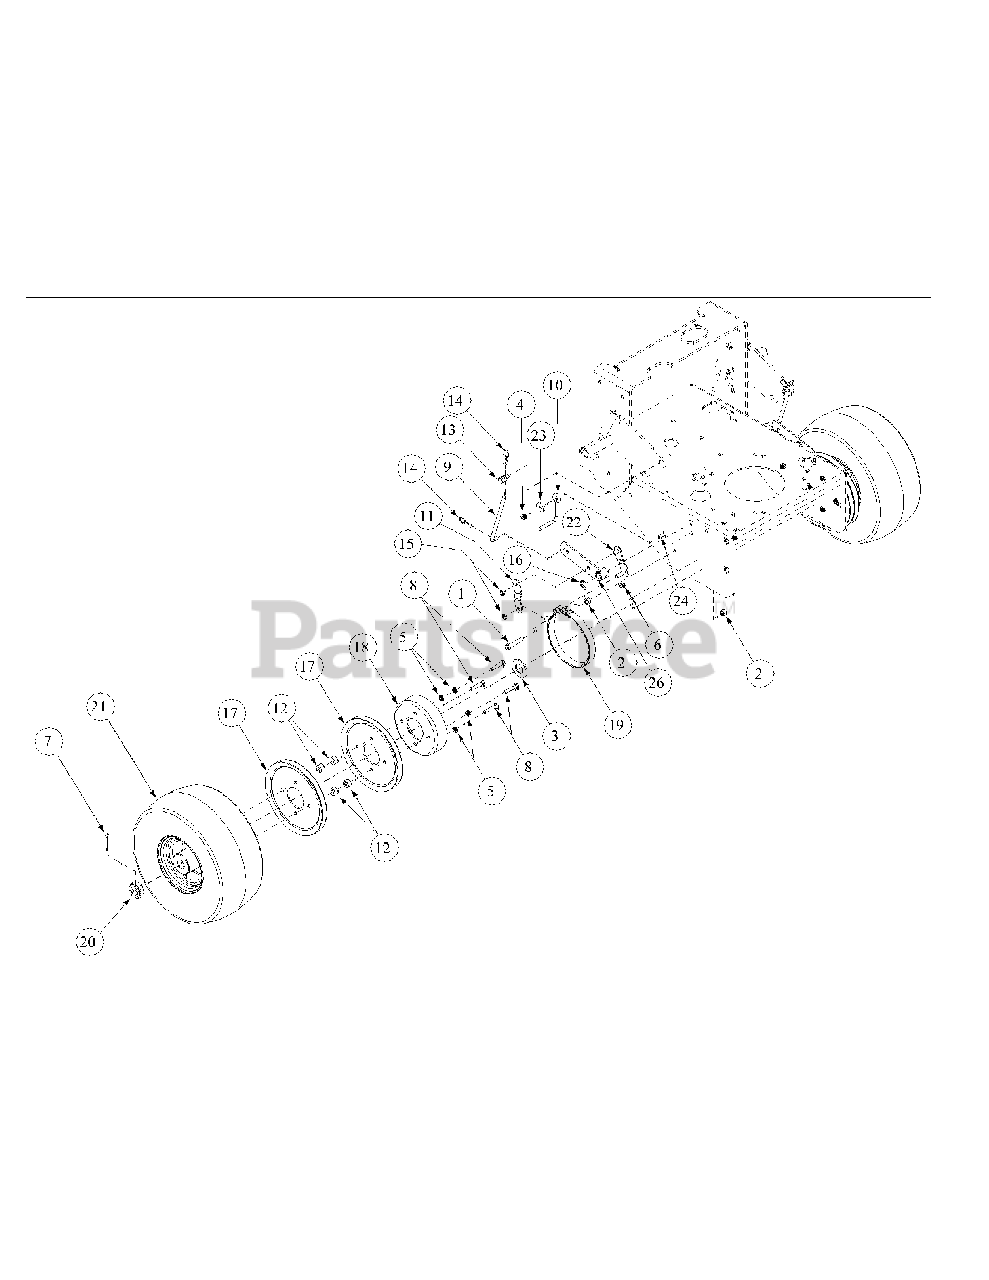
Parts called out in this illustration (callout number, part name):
1	Hex Cap Screw, 3/8-16, 2.00
2	Hex Nut, 3/8-16
3	Flat Washer, 2.000 x 1.005 x .120
4	Nut, Nylock, 5/16-18
5	Lock Washer, 5/16 Zinc
6	Grease Fitting, 1/4-28, 90 degree
7	Cotter Pin, 5/32 x 1-1/2 Zinc
8	Hex Cap Screw, 5/16-18 x 1-1/2
9	Brake Rod
10	Drive Belt Guide
11	Brake, Bracket Link
12	Drive Wheel Pulley Spacer
13	Swivel Joint
14	Hair Pin, 3/8-1/2
15	Retainer, Push ON, 3/8
16	E-Ring, 5/8
17	Drive Pulley, V
18	Drum Brake
19	Band Brake
20	Hex Jam Nut, 1-14
21	Wheel Assembly, 13 x 5.00-6
22	Brake Link
23	Idler Washer
24	Carriage Bolt, 5/16-18 x 1
26	Brake Lever Weldment
